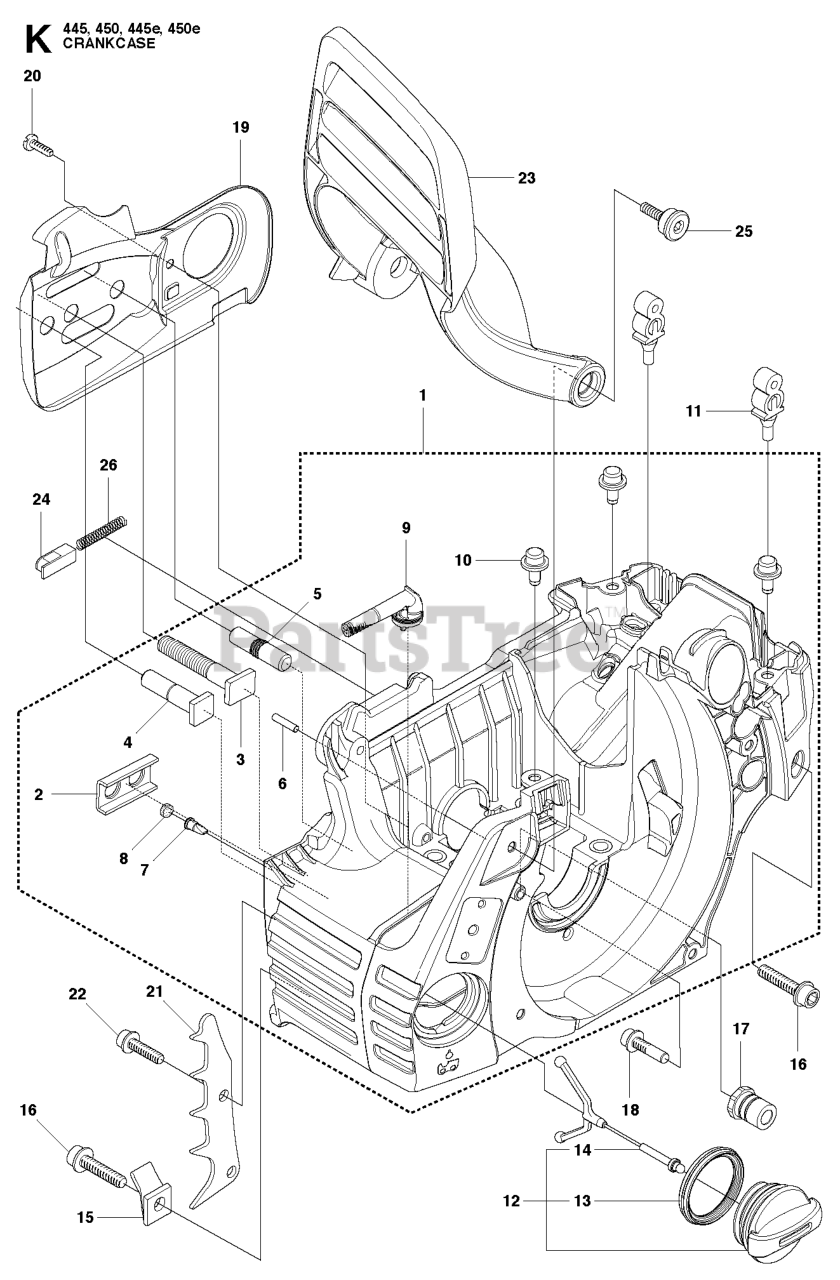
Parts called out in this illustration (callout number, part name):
2	STIFFENING PLATE
7	VALVE-CHECK (DUCKBILL)
8	PLUG
9	OIL SCREEN
12	TANK CAP ASSY
15	CHAIN CATCHER
16	SCREW IHSCFT
17	LATERAL SUPPORT
18	SCREW IHSCFT
19	CHAIN GUIDE PLATE
23	HAND GUARD
26	LOCK SPRING
